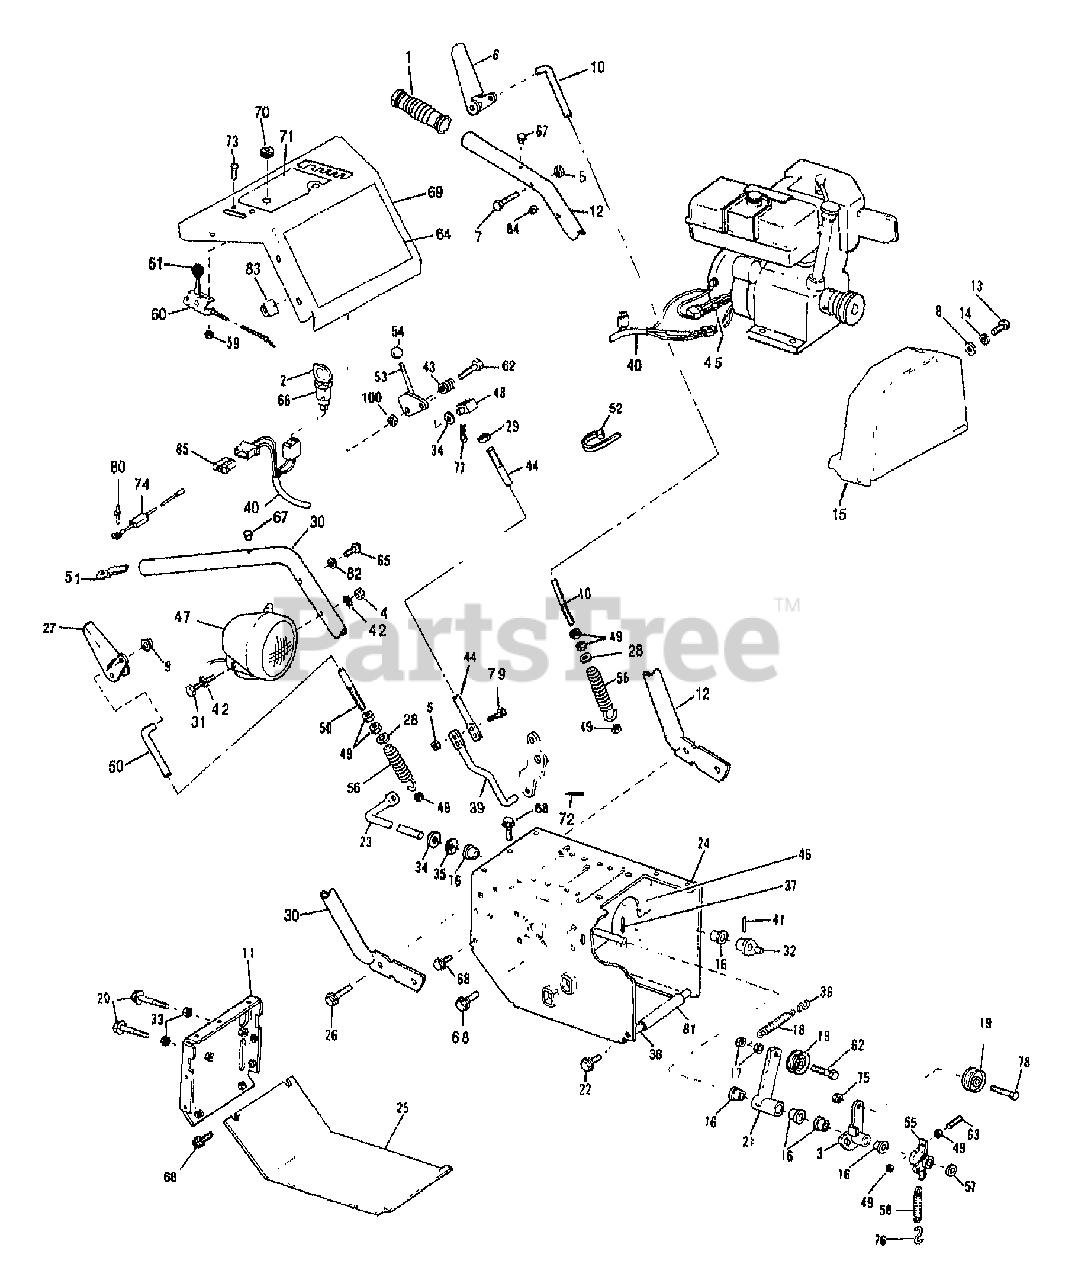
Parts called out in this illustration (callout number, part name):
1	GRIP-HANDLE
3	ARM-IDLER
4	NUT-TOP/LK 5/16-18 ZP
5	NUT-HT LK 1/4-20
6	LEVER-CONTROL
7	SCR-HH 1/4-20X1.75 G5 ZP
8	WASHER-FLAT 5/16 SAE
9	NUT-PUSH
10	ROD-WHL DRIVE CLUTCH
12	HANDLEBAR-LH
13	SCR-HHC 5/16-18X.75 GR 5 ZP
14	WASHER-LK .312 ZP
16	BUSHING-.5X.21 NYLON FLNG
17	NUT-HEX/JAM 3/8-16 ZP
18	SPRING-EXTENSION
19	PULLEY-IDLER
20	SCR-HFLK 5/16-18X1.75 ZP G5
21	ARM-IDLER
22	SCR-HFLK 5/16-18X.75 ZP
25	COVER-BOTTOM
27	LEVER-CONTROL
28	WASHER-LK .25 ZP
29	NUT-HEX 3/8-16 ZP
30	HANDLEBAR-RH
31	SCR-HH 5/16-18X4.0 G5 ZP
33	NUT-HEX JAM 5/16-18
34	WASHER-FLAT .88X.5X.06 ZP
36	HOOK-J
38	BRACE-CROSS
39	ROD-LOWER CONTROL
42	WASHER-LK .312 EXT TOOTH
43	SPRING-COMPRESSION
44	ROD-SPEED CONTROL
45	CONNECTOR
47	ASSM-LIGHT
48	BLOCK-SWIVEL
49	NUT-HEX 1/4-20 ZP
50	ROD-AUGER CLUTCH
51	CLAMP
52	TIE-CABLE NYLON BLACK
53	LEVER-SPEED CONTROL
55	ASSM-BRAKE ARM
56	SPRING-EXTENSION
57	WASHER-1.06X.531X.1 ZP
58	SPRING-EXTENSION
59	NUT W/LKWASHER 10-24 ZP
60	CABLE-THROTTLE BLNS SNOWTHR
61	KNOB
62	SCR-HH 3/8-16X1.75 G5 ZP
63	SCR SET-HXSKT 1/4-20X1.25
64	DECAL-LOGO
65	SCR-FLANGE 1/4-20X3/4 GR5
66	SWITCH-IGN W/HDW & KEYS
67	BUMPER-RUBBER
68	SCR-HFLK 5/16-18X.75
69	ASSM-CONSOLE
70	GROMMET-FLIP
71	DECAL-INST
72	PIN-COTTER .09X.75 ZP
73	SCR-TRUSS #10-24 X 5/8
74	ASSM-RESISTOR
75	NUT-LOCK 3/8-16
77	CLIP-HAIRPIN .07 DIA
78	SCR-HH 3/8-16X1.5 G5 ZP
79	SCR-HH 1/4-20X.75 G5 ZP
80	RIVET-POP .125
81	TUBE-PLASTIC
82	WASHER-FLAT 1/4 SAE
83	CLIP-CORD
84	BUSHING
85	CONNECTOR
